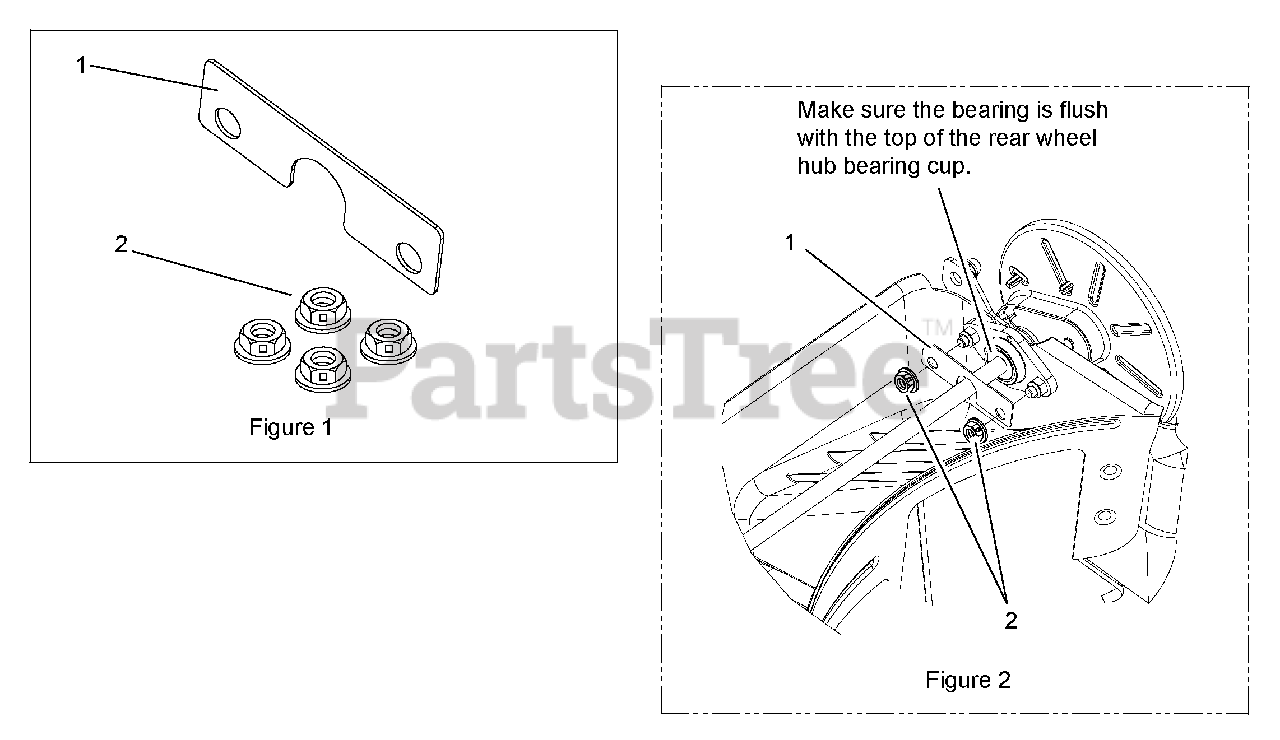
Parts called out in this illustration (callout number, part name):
1	KIT, BEARING RETENTION
1	BRACKET, BEARING RETENTION
2	NUT-LK-CTR .375-24 YWZC
